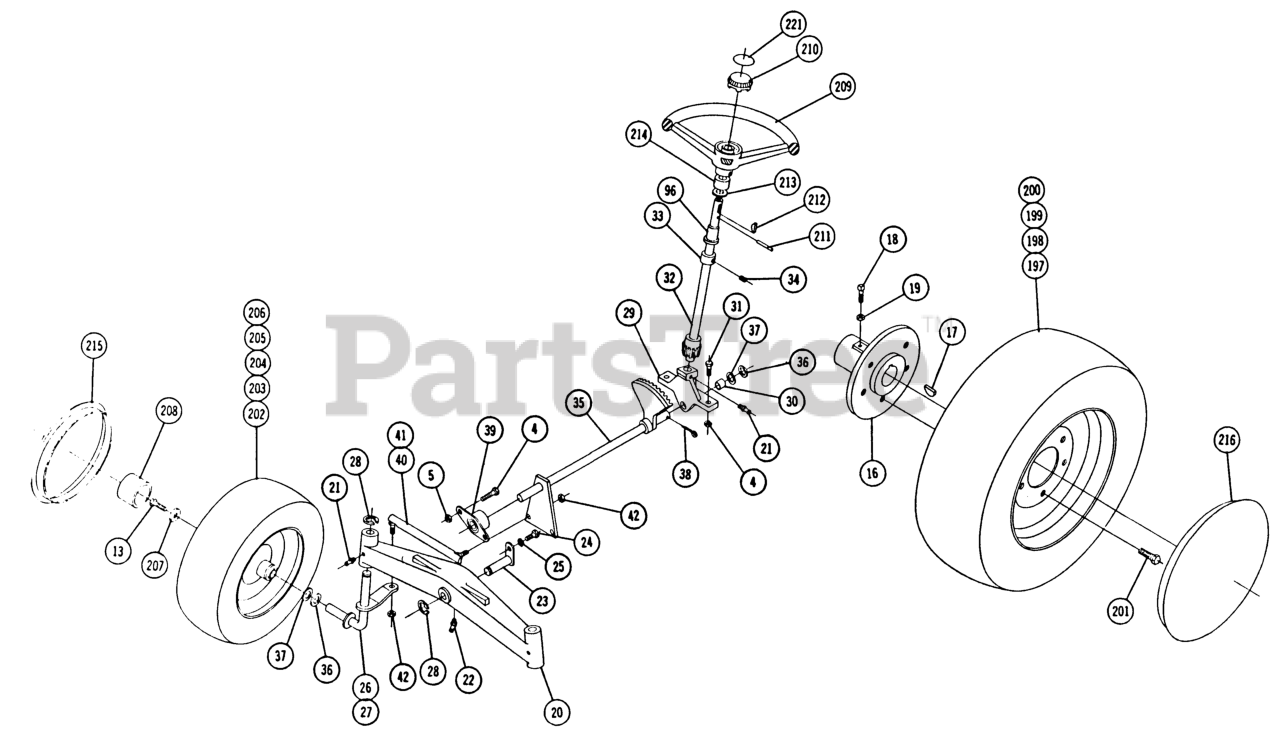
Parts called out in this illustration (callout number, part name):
1	Ass-y.Frame
1	Case RH
2	BEARING-NEEDLE
2	Hoodstand
3	BALL BRG 1 1/2 I.D.
3	Cover-Dust
4	Bearing-Axle
4	Bolt 3/8-16 x 1
5	SEAL-OIL
5	3/8-16 E.S.
6	SEAL BRAKE SHAFT
6	Bolt 5/16-18 x
7	PIN-DOWEL
7	Nut-Nylok
8	Pulley
8	Case LH
9	NEEDLE BEARING
9	Set Screw, 5/16-18 x 5/16
10	End Cap-RH
10	WOODRUFF KEY
11	End Cap-LH
11	Bolt 3/8-16 x 7/8
12	Axle, R.H.
12	Lockwasher
13	Axle, L.H.
13	Bolt 3/8-16 x 7/8
14	Tool Box
14	SNAP RING
15	THRUST WASHER
15	Bolt 3/8-16 x 3/4
16	Hub Wheel
16	SIDE GEAR
17	Gear-Ring
17	WOODRUFF KEY
18	Body
18	Screw-Set
19	3/8-16 Jam Nut
19	SPIROL ROLL PIN
20	AXLE-FRONT
20	PINION
21	Zerk
21	Spring
22	FITTING-GREASE
22	Bolt Hex 3 1/4
23	PIN AND PLATE ASM
23	3/8-16 E.S.
24	Bolt Hex 5/16-18
24	Washer
25	Gear
25	Lockwasher
26	R.H. Spindle
26	GEAR
27	L.H. Spindle
27	Gear-33T
28	E-RING
28	SHAFT GEAR
29	Support
29	Snap Ring
30	BEARING-BRONZE
30	Key
31	Assy.-Park Brake
31	Bolt 3/8-16 x 1
32	GASKET
32	ASSY UPPER STEER R
33	Collar
33	Bolt Hex 3/8-16 x 5
34	Bolt, 3/8 16 x 2
34	Set Screw 1/4-20 x 1/4 Nylok
35	Assy-Steering
35	Bolt Hex 3/8-16 x 1
36	WASHER-SHIM
37	WASHER
37	Bolt, 3/8-16 x 1
38	Assy. Lever-Brake
38	Cotter Pin
39	BEARING-FLANGED
39	Pin-Roll
40	Tie Rod-R.H.
40	Filter
41	Tie Rod-L.H.
41	FITTING
42	Strainer
42	Locknut 3/8-24
43	Dipstick
43	Pedal
44	BUSHING
44	Nipple 1/2 Pipe x 31/2
45	Gasket
45	Coupling 1/2 Pipe
46	GASKET PUMP
46	Hairpin
47	Hairpin
47	PLUG 1/4 PIPE ALLEN
48	Hydrogear
48	Roll Pin
49	Collar
49	SUPPORT CAM BLOCK
50	ever Brake
50	SHCS 1/4-20 X 1/2
51	Shim
51	Washer
52	E Ring
52	O-Ring
53	Arm-Cam Follower
53	Idler Arm
54	BUSHING-FLANGED
54	ROLL PIN 1/4 X 1-1/4
55	Bolt 1/4-20 X 3/4
56	ECC CAM FOLLOWER
56	Nut-Jam 1
57	Set Screw-1/4-20 x 1/2
57	Lockwasher
58	TENSION PLATE
58	Handle-Brake
59	KNOB
59	Bolt-Rd. Heed #8-32 x 1/2
60	CAM
60	Conduit
61	Hitch
61	Washer
62	Pin
62	Lockwasher
63	SPIROL PIN
63	RING-SNAP, EXTERNAL
64	VALVE
64	SPACER
65	RING BACK UP
65	BATTERY BOX ASSY R (NS)
66	LINK BATTERY CLAMP
66	O-Ring
67	PLUG
67	Nut-Nylok
68	Ass-y Dampening Valve & Ring
68	Washer
69	SPRING-BRAKE
69	O RING
70	Idler Pulley
70	O RING
71	Ass-y Piston & Sleeve (Matched)
71	SPACER-BRAKE LINK
72	Bolt 3/8-16 x 1 5/8
72	O RING
73	SPRING
73	Cam Control Arm
74	Indicator-Speed
74	SPRING
75	SUNDSTRAND 3100047
75	Bolt, 1/4-x 1/2
76	Cone-Relief Valve
76	Bearing
77	PIN
77	SLEEVE RELIEF VALVE
78	O RING
79	Cam Pivot Rod
79	Plug
80	FRICTION COLLAR
80	SPRING-SUNDSTRAND
81	COLLAR BRKT PIVOT
81	Valve
82	FRICTION CONE
82	Spring Charge Pump Valve
83	SPRING FRICTION
83	Cone
84	Collar Friction
85	Nut 3/1-10 Jam
85	O RING
86	SEAL
86	WOODRUFF KEY
87	Cam Plate
88	Spacer
89	NYLINER BUSHING
90	SHIM-WASHER
91	Spring
92	Housing
93	Support-Fuel Tank
94	Bolt Hex 5/16-18
95	Bolt 1/4-20 x 5/8 Whizlock
96	Bushing
97	Grommet
98	Panel
99	SPEED NUT
100	Screw-Self #10 10-16
101	Fuel Tank
102	Clamp-Tank
103	Cap
105	Nut Square
106	S/A FUEL VALVE
107	Hose
108	Clip
109	CLAMP CORBIN 7/16
110	Fuel Hose
111	Engine 12 H.P.
112	Bolt Hex 3/8-16 x 1 1/2
113	Nipple
114	ELBOW-STREET
115	Cap
116	MUFFLER
117	Nipple 1" Pipe x 2"
118	Nipple 1 Close Pipe
119	Elbow 1" x 45
120	Pulley-Engine
121	Key
122	Nut 5/16-18
123	Control Choke
124	Control Throttle
125	Lockwasher 9/16
126	RING NUT
127	SWITCH
128	Nut
129	Lockwasher 6/16
130	Insulator
131	Key-EL
132	Cigar Lighter
133	Knob & Plug
134	SHELL CLAMP
135	Socket
136	Nut #8-32
137	LOCKWASHER
138	Wire
139	Battery
140	Harness-Wiring
141	Ground Wire
142	ASSY REFLECTOR HOUSI
143	WIRE ASSY
144	SPRING
145	BULB
146	Lens
147	Pan HD Swage
148	Switch
149	Harness
150	SPEED CLIP
151	CONNECTOR 3 WIRE
152	CLIP-WIRE
153	Base
154	Lens
155	Bulb
156	Mounting Pad
157	CONNECTOR 2 WIRE
158	Bolt #10-32
159	Nut #10-32
160	Lockwasher #10
161	Belt Guard
162	Bolt Hex 7/16-4 x 3/4
163	Lockwasher 3/8
164	Bracket
165	Bolt, 5/16-18 x 1/2
166	Footrest R.H.
167	Footrest L.H.
168	BRACKET
169	Bolt-Carriage 5/16-18
170	Latch Fender
171	Spring
172	NYLINER BUSHING
173	Pin
174	BRACKET FENDER LATCH
175	Nut, 1/4-20
176	Cover Plate
177	Bolt, 1/4-20 Whizlock
178	Fender
179	SPACER
180	GROMMET
181	Seat
182	Washer
183	Ass-y Hood
184	Hood-Hinge
185	NYLINER BUSHING
186	Rod Pivot
187	LEVER HOOD LATCH
188	KNOB
189	SPIROL PIN
190	Roller Rubber
191	Roller
192	Nut-Hi Crown
193	SPEED NUT
194	Rod Latch
195	Hood Ornament
196	SPEED NUT
197	Wheel and Tire
198	Wheel
199	Tire
200	VALVE TUBELESS
201	Lug Nut
202	Wheel, Tire & Tube
203	WHEEL RIM
204	Bearing
205	Tire
206	Tube
207	WASHER
208	Hub Cap
209	Steering
210	CAP INSERT
211	ROLL PIN 1/4 X 1-1/4
212	Key
213	WASHER-BOWED
214	COLLAR
215	Disc 8" Wheel
216	Disc 12" Wheel
217	Decal Charger Auto Drive
218	Decal-Hood Trim R.H.
219	Decal-Hood Trim L.H.
220	Decal
221	Decal
222	Decal Free Wheeling
223	Decal
224	Pin-Tool
225	V BELT
226	Clip
227	SPACER
228	Bolt 1/4-20 x 3/8
229	Special Nut
